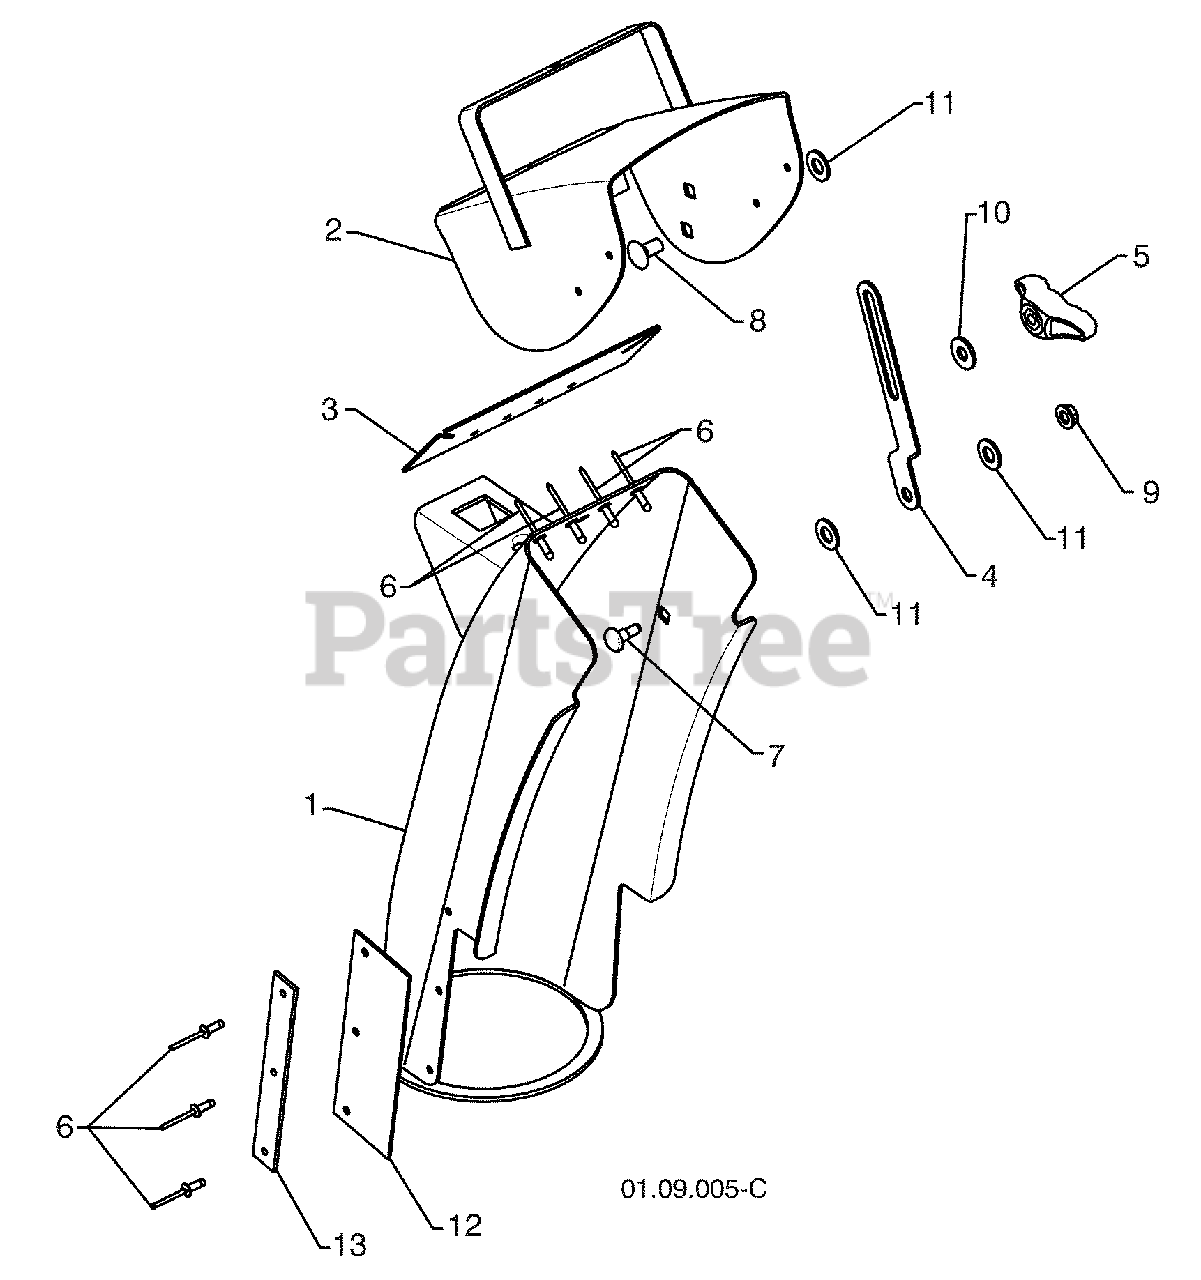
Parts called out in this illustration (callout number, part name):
1	CHUTE WELDMENT
2	DEFLECTOR WELDMENT
3	DEFLECTOR SEAL
4	STRAP
5	KNOB BLACK
7	SHOULDER BOLT 1/4-20 X .704
8	CARRIAGE BOLT 5/16-18 X .625
9	NUT 1/4-20
11	PLASTIC WASHER
12	CHUTE SNOW SHIELD
13	SHIELD RETAINER STRAP
